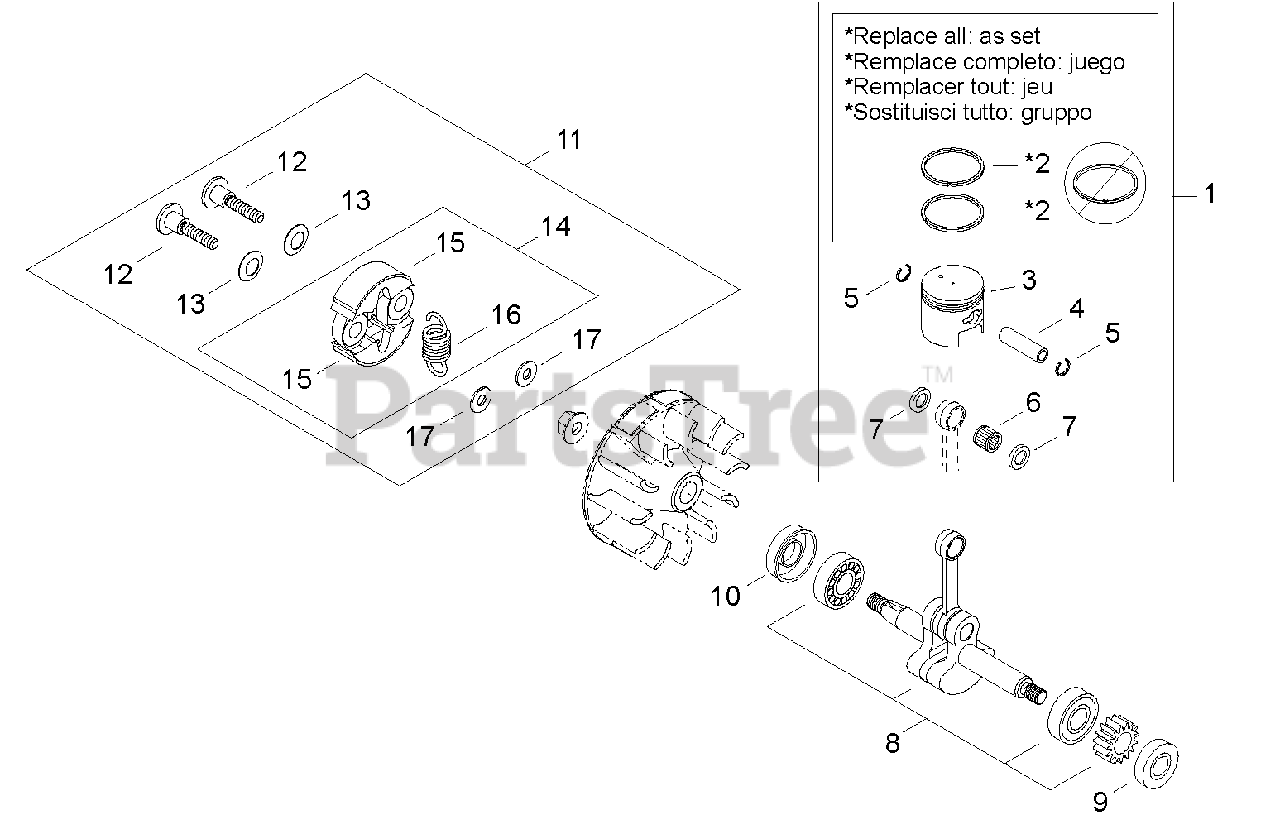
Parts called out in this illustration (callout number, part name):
1	PISTON KIT
2	RING, PISTON
3	PISTON
4	PIN, PISTON
5	RING, SNAP
6	BEARING, NEEDLE 9
7	WASHER, THRUST 9
8	CRANKSHAFT ASSY
9	SEAL, OIL 12
10	SEAL, OIL 12
11	CLUTCH ASSY
12	BOLT, CLUTCH
13	WASHER, SPRING
14	SHOE ASSY, CLUTCH
15	SHOE, CLUTCH
16	SPRING, CLUTCH
17	WASHER 6 MM
